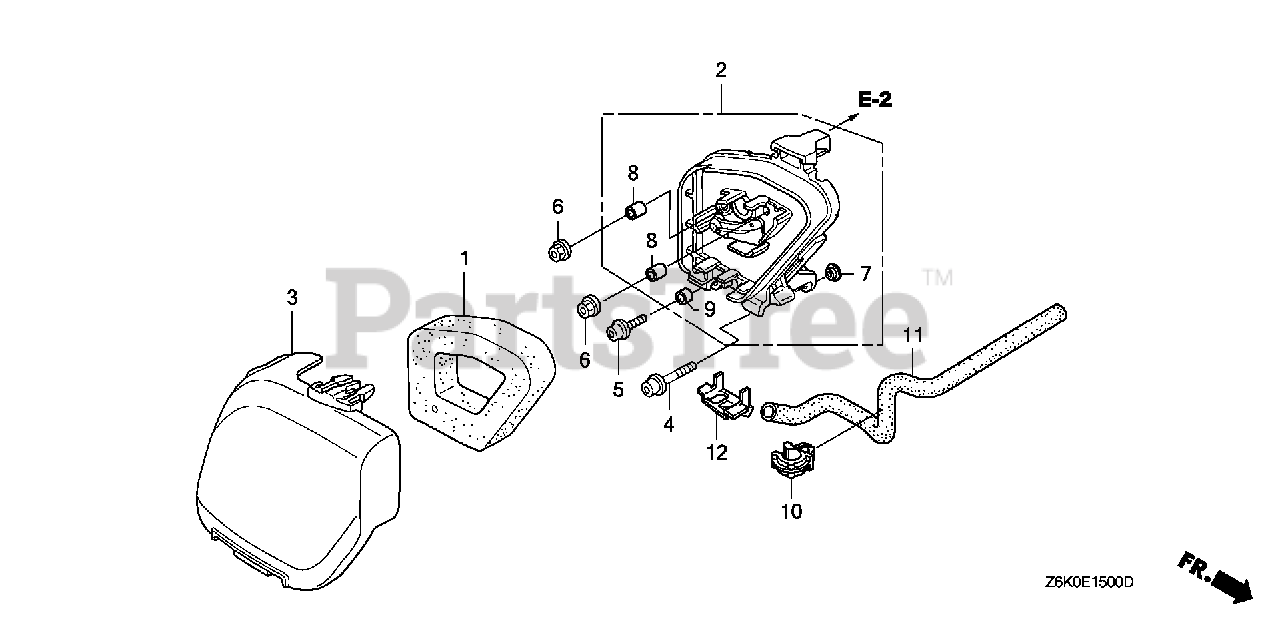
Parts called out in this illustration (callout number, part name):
1	ELEMENT, AIR CLEANER
2	HOUSING, AIR CLEANER
3	COVER, AIR CLEANER
4	BOLT, SOCKET (5X25)
5	BOLT, SOCKET (5X16)
6	NUT, FLANGE (5MM)
7	COLLAR, AIR CLEANER HOUSING
8	COLLAR, AIR CLEANER
9	COLLAR A, HEAD COVER
10	CLIP, TUBE
11	TUBE, HOT AIR
12	JOINT, HOT AIR
